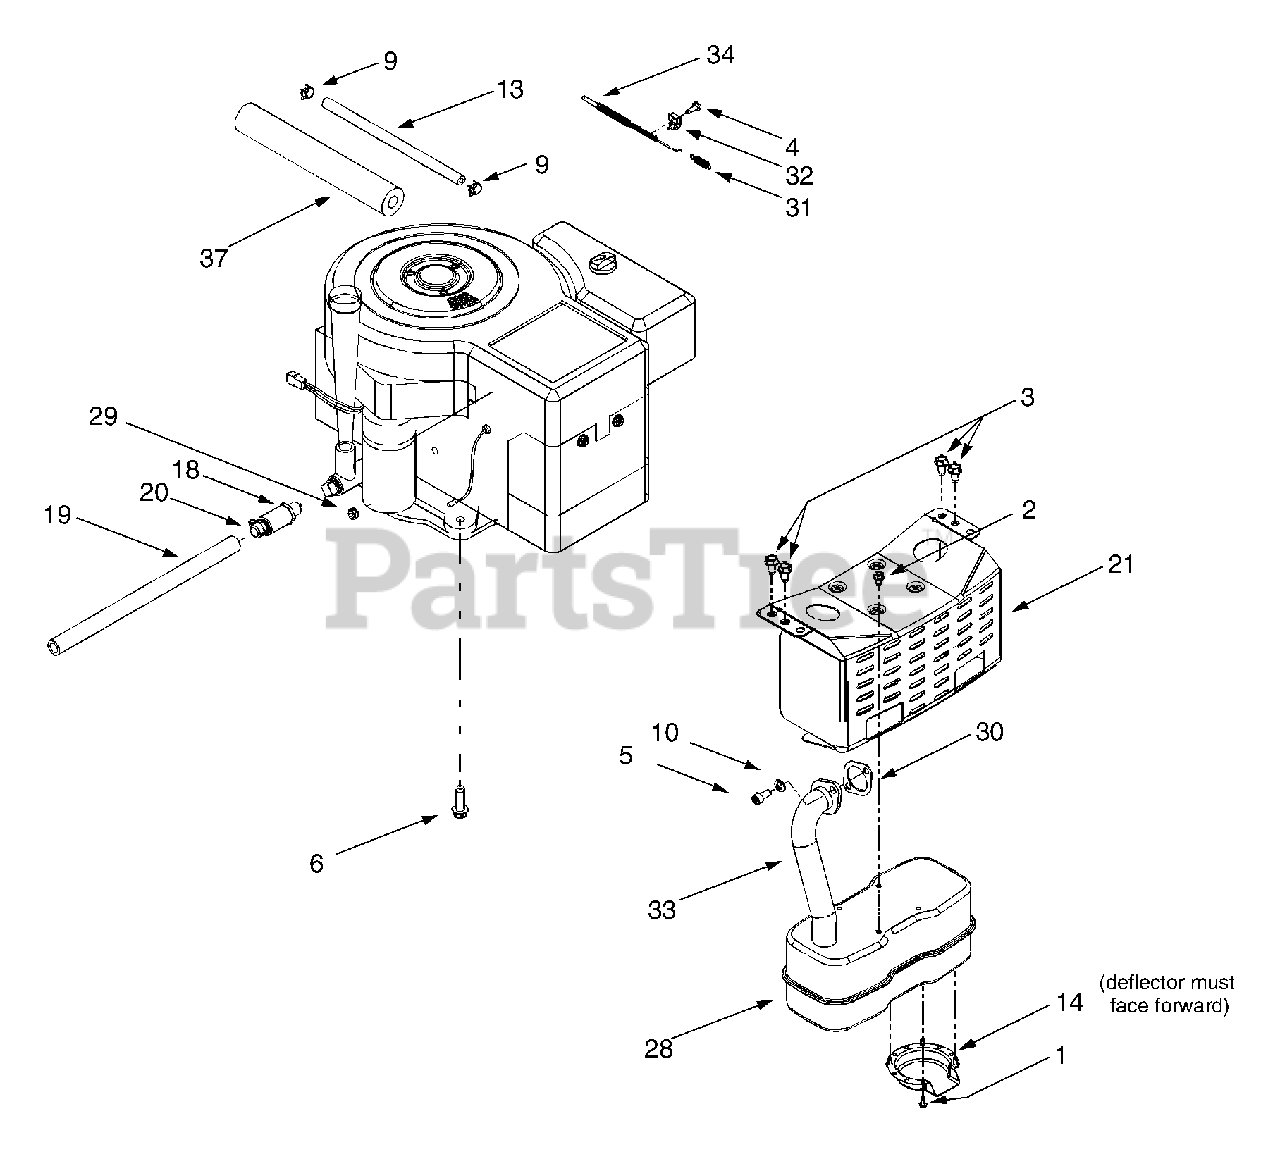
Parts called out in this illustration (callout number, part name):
1	Self-tapping Screw, #8-32 x .375
2	Self-tapping Screw, 1/4-20 x .5
3	Self-tapping Screw, 5/16-18 x .625
4	Screw, #10-32 x .625
5	Socket Cap Screw, 5/16-18 x .625
6	Self-tapping Screw, 3/8-16 x 1.25
9	Hose Clamp
10	Lock Washer, 5/16
13	Fuel Line Hose
14	Muffler Deflector
18	Oil Drain Valve
19	Oil Drain Hose
20	Oil Drain Cap
28	Muffler, Single Inlet
29	Hex Sems Nut, 1/4-20
30	Exhaust Gasket
31	Extension Spring, .275 x 1.25
32	Casing Clamp
33	Exhaust Pipe
34	Throttle/Choke Cable
37	Foam
